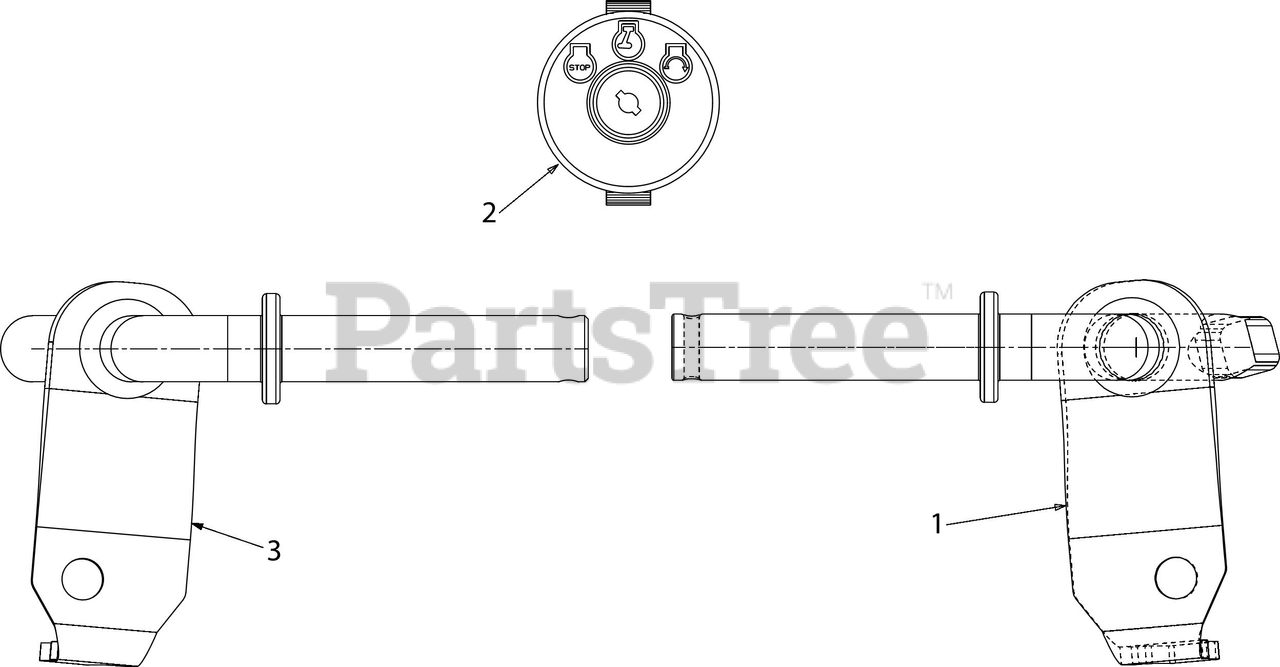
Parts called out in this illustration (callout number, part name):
1	FRONT AXLE ASSEMBLY (RH)
2	3 POSITION KEY SWITCH
3	FRONT AXLE ASSEMBLY (LH)
